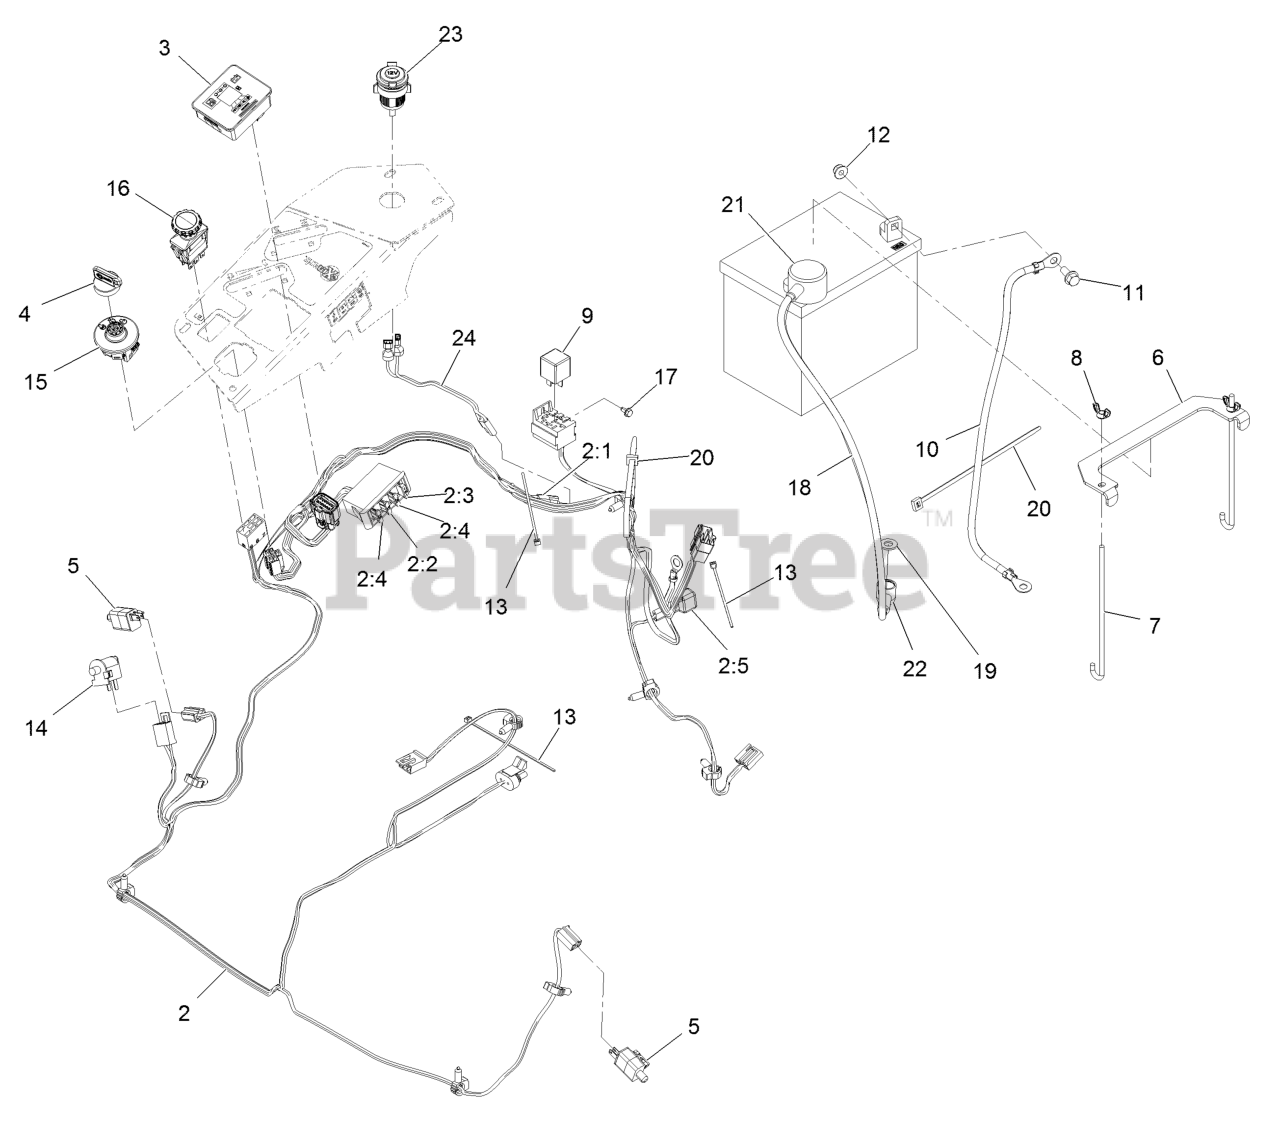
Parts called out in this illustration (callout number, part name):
2	HARNESS-WIRE, MAIN
2:2	FUSE-BLADE, 10 AMP
2:3	FUSE-BLADE, 15 AMP
2:4	FUSE-BLADE, 25 AMP
2:5	CAP-PLUG
3	FUEL/HOUR METER ASM
4	KEYS-IGNITION (SPARE PAIR
4	KEY-IGNITION
6	STRAP-TIE DOWN, BATTERY
7	BOLT-HOLDDOWN
8	WINGNUT
10	CABLE-BATTERY, NEGATIVE
11	SCREW-HHF
12	NUT-HF, NI
13	TIE-CABLE
14	SWITCH-BAIL
16	SWITCH-PTO, 10 AMP
17	SCREW-HWH
18	CABLE-BATTERY, POSITIVE
19	WASHER-FLAT
20	TIE-PLASTIC
21	INSULATOR-BATTERY
22	INSULATOR-SOLENOID
23	RECEPTACLE-12V
24	HARNESS, RECEPTACLE 12V
